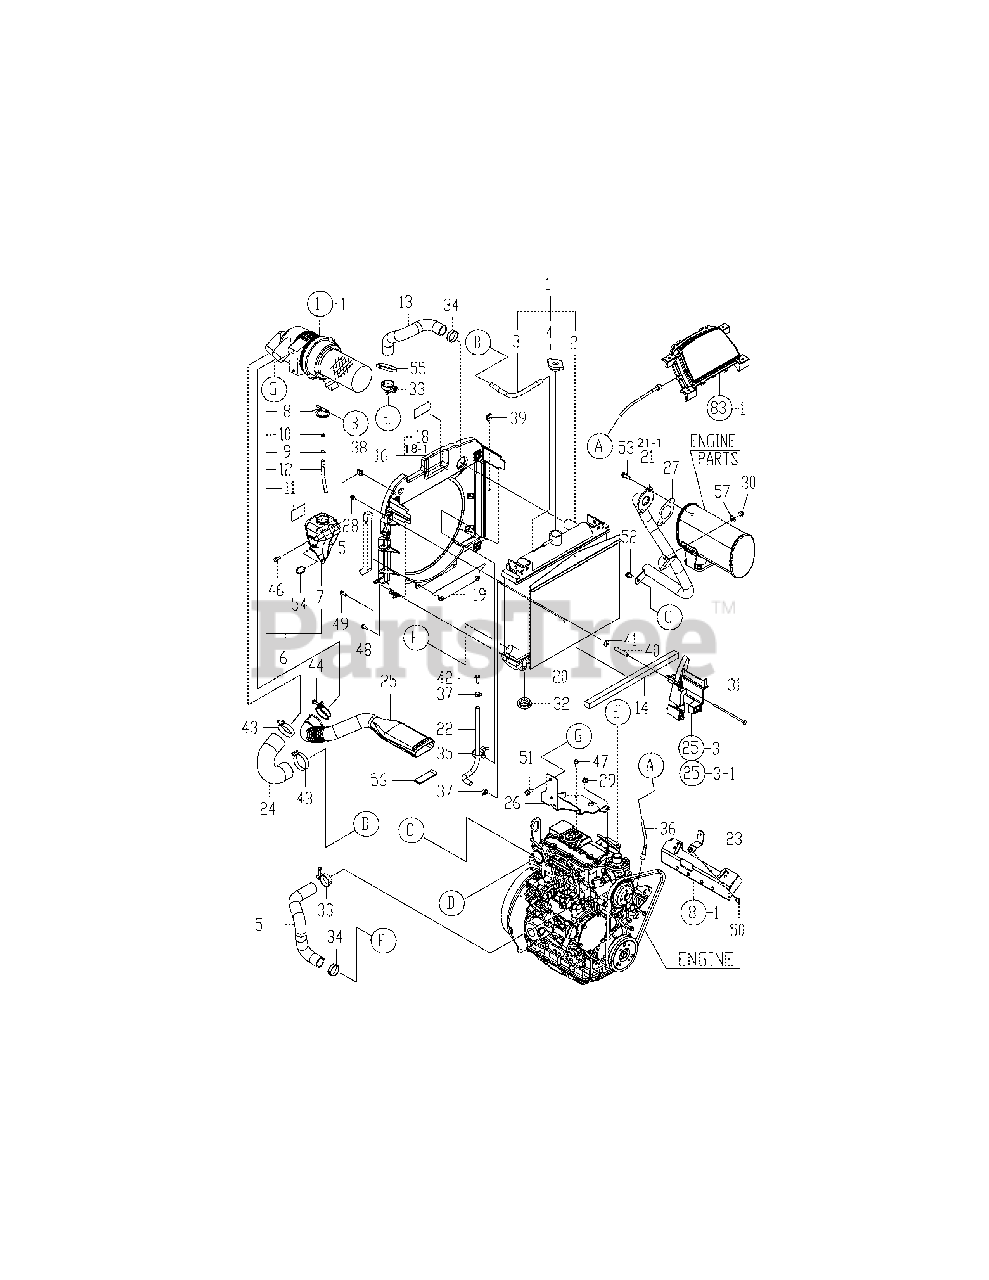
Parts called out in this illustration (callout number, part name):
5	Pipe, Water 66
6	Tank Assy, Coolant
9	Retainer, Pipe
11	Label, Sub-Tank
13	Hose, Cooling Water
14	Seal, Radiator
15	Seal, Shroud Lower
16	Shroudm Assy, Fan
18	Label, Warning, Fan
18-1	Label, Warning, Fan
19	Plate Assy, Shroud
20	Screen, Radiator
24	Hose, Air Intake
25	Air Intake Pipe
26	Bracket, Air Cleaner
27	Gasket, Exhaust
32	Rubber, Radiator
34	Clip, Hose 31.0
36	Cable, Hour Meter
37	Clamp, Hose 12
40	Coller, 6.5X10X52
43	Clamp, Hose 54
44	Clamp, Hose 50
56	Seal E, Ladiator
57	Washer 8, Polished
